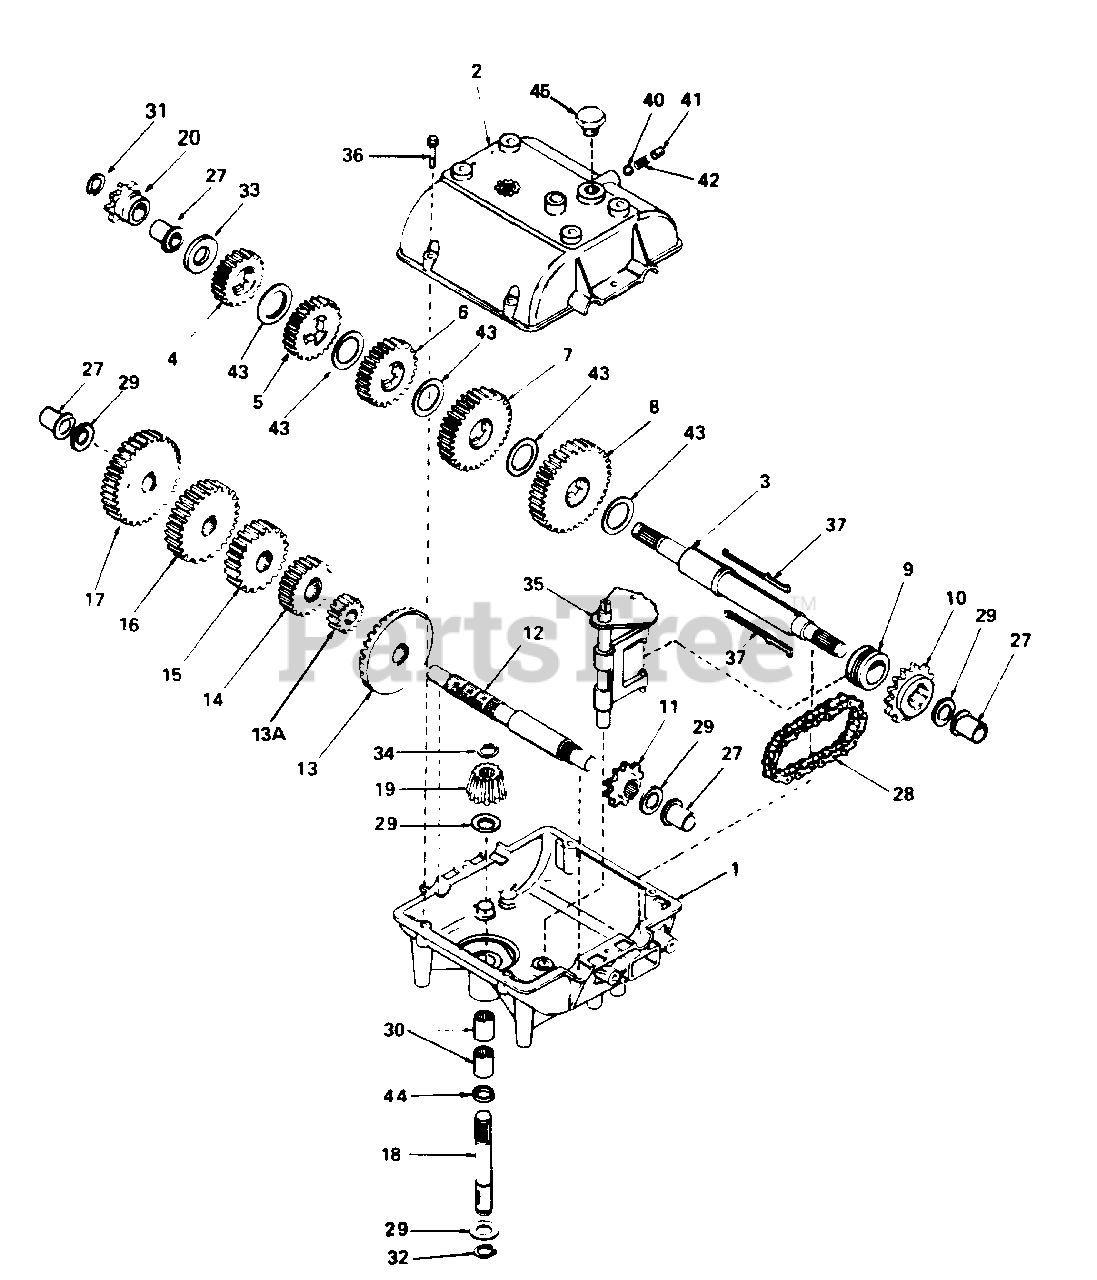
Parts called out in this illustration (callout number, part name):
1	CASE, TRANSMISSION
2	COVER, TRANSMISSION
3	SHAFT, OUTPUT
4	GEAR, SPUR (20 TEETH)
5	GEAR, SPUR (22 TEETH)
6	GEAR, SPUR (25 TEETH)
7	GEAR, SPUR (30 TEETH)
8	GEAR, SPUR (35 TEETH)
9	COLLAR, SHIFT
10	SPROCKET (18 TEETH)
11	SPROCKET (9 TEETH)
12	SHAFT, COUNTER
13	GEAR, BEVEL (42 TEETH)
13A	GEAR, SPUR (15 TEETH)
14	GEAR, SPUR (20 TEETH)
15	GEAR, SPUR (25 TEETH)
16	GEAR, SPUR (28 TEETH)
17	GEAR, SPUR (30 TEETH)
18	SHAFT, INPUT
19	BEVEL PINION, INPUT
20	SPROCKET (12 TEETH)
27	BUSHING, FLANGED
28	CHAIN, ROLLER (NO. 41 CHAIN, 24 LINKS)
29	WASHER, THRUST
30	BEARING, NEEDLE
31	RING, RETAINING
32	RING, RETAINING
34	RING, RETAINING
35	ROD & FORK ASSEMBLY, SHIFT
36	SCREW, HEX HD. TAPTITE, 1/4-20X1-1/4
40	BALL, STEEL 5/16
41	SCREW, SET 3/8-16X3/8
43	WASHER, THRUST
